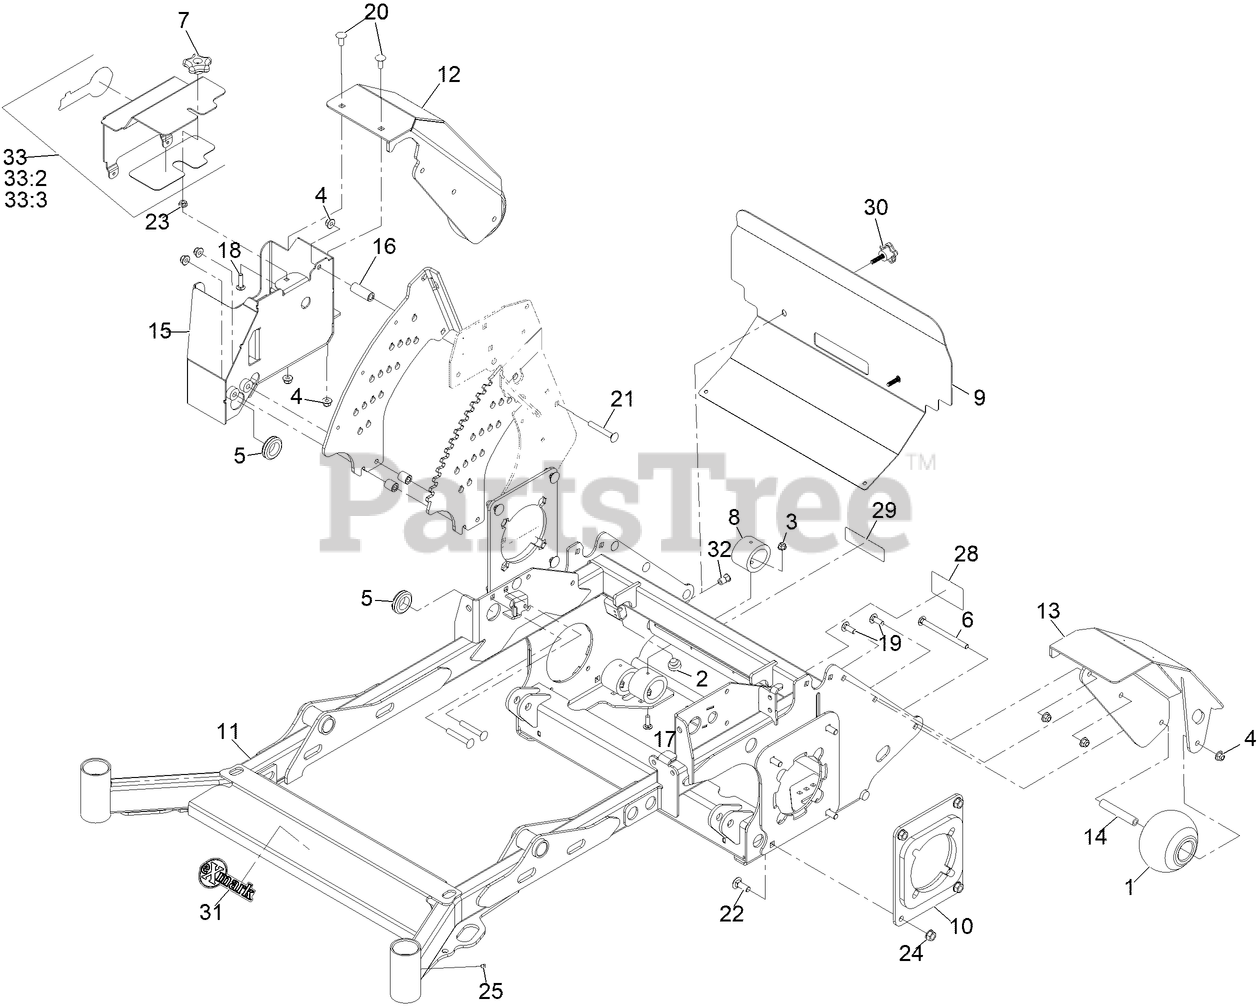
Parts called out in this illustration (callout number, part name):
1	ROLLER-SCALP, ANTI
2	BUMPER-RUBBER
3	NUT-HF, NI
4	NUT-HF, NI
5	GROMMET
6	BOLT-CARR
7	KNOB-HANDLE
8	BUMPER-ISOLATOR
9	GUARD-REAR FOOT
10	WLD-MTR MOUNT 48/52
11	MAINFRAME ASM -48/52
12	FENDER- WHEEL RH
13	FENDER- WHEEL LH
14	SPACER- ROLLER
15	WELD-BATTERY BOX
16	SPACER- ROLLER
17	BOLT-CARR
18	SCREW-CARR
19	SCREW-CARR
20	SCREW-CARR
21	SCREW-CARR
22	BOLT-CARR
28	DECAL-DRIVE RELEASE
29	DECAL-COVER, MISSING
31	DECAL-EXMARK LOGO
32	NUT-CLINCH
33	ASM-LID BATTERY W/PAD
33:2	PAD-BATTERY BOX LID
33:3	DECAL-EXMARK LOGO
